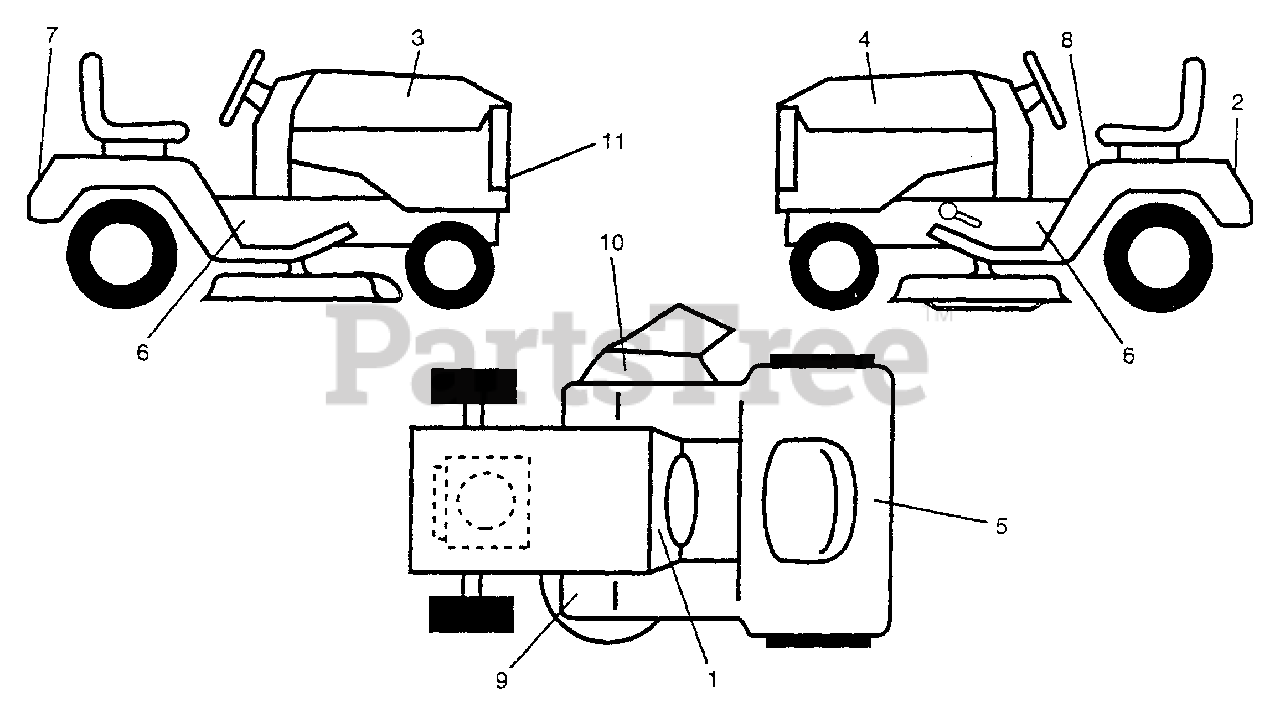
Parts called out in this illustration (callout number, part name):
1	Decal Instruction Dash Eng/fr
2	Decal USA White
3	Decal Hood RH Husq
4	Decal Hood LH Husq
5	Decal Caution Battery Fr/ger
6	Decal Chassis Lawn Tractor
7	Decal Fender Husqvarna
8	Decal Caution Fender Eng/fr
9	Decal Clutch/brake Eng/fr
10	Decal Warning MULT-LANGUAGE
11	Decal Grille Husqvarna "h" logo
